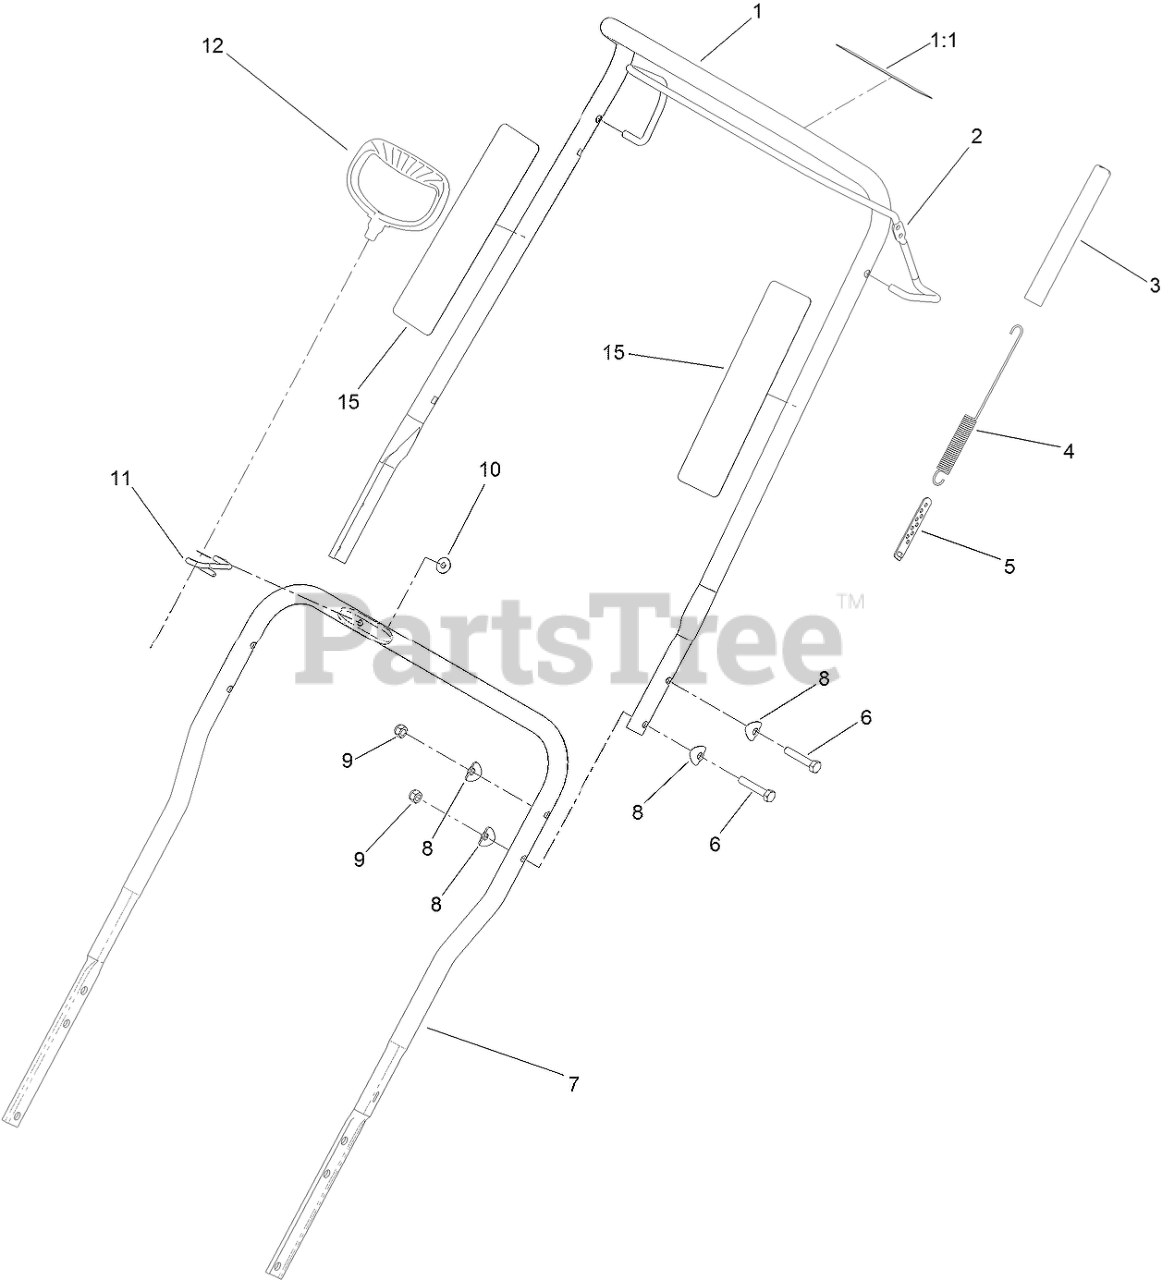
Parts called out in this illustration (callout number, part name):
1	UPPER HANDLE ASM
1:1	DECAL-DRIVE, ROTOR
2	BAIL-CONTROL
3	COVER-SPRING
4	SPRING-EXTENSION, CLUTCH
5	ADJUSTER-CLUTCH CABLE
6	SCREW-HH
7	HANDLE-LOWER
8	WASHER
9	NUT-LOCK, NI
10	NUT-HF
11	GUIDE-ROPE
12	HANDLE-RECOIL
15	DECAL-TAPE, REFLECTIVE
